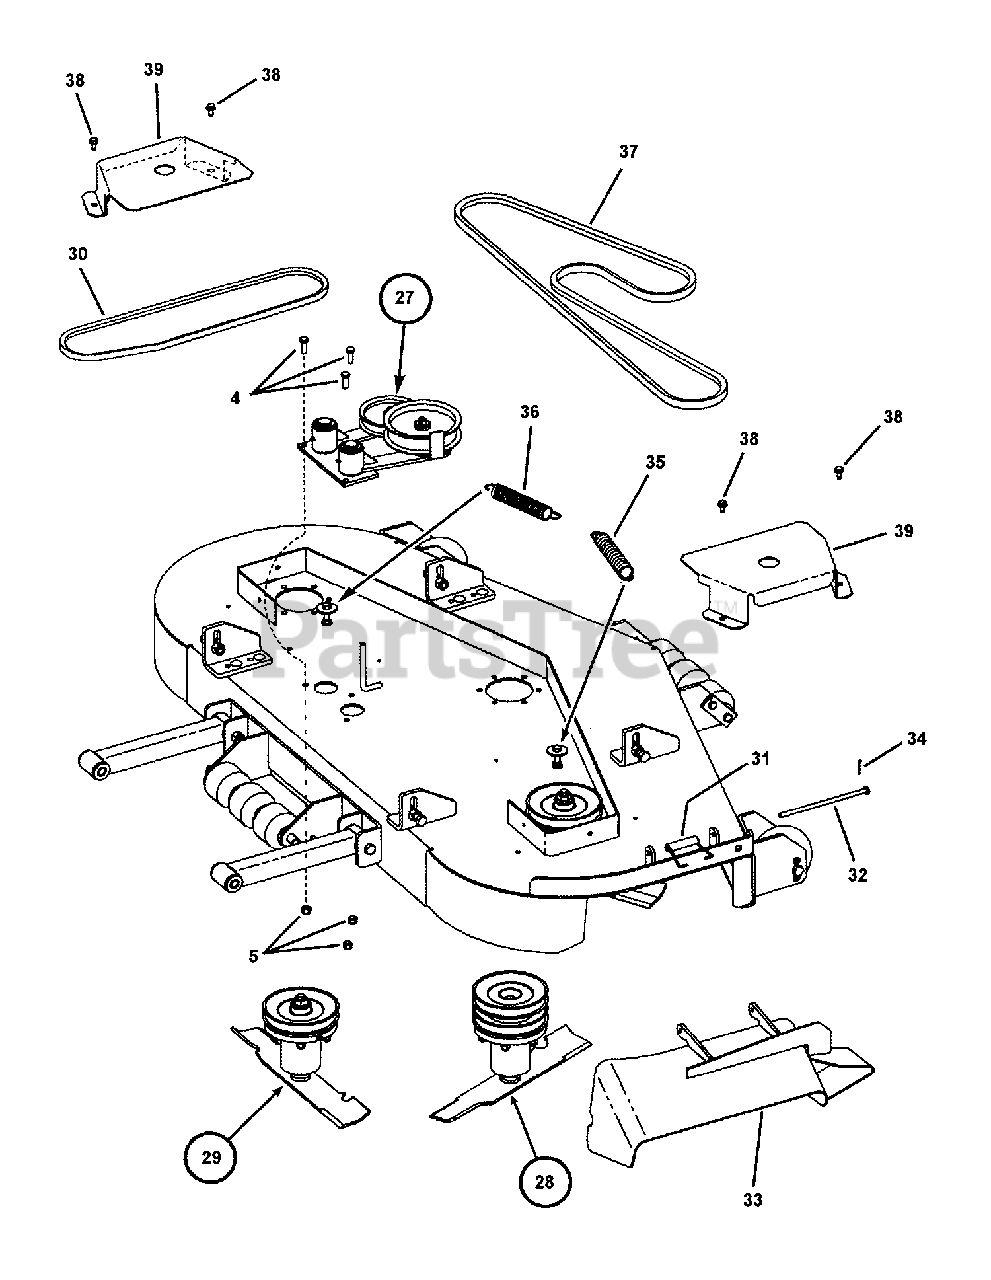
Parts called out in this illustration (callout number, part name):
4	BOLT, 3/8-16 X 1" GD5 CZ
5	NUT, 3/8-16 HEX NYLON LOCK
27	ASSEMBLY, Idler (see breakdown on Idler Assy page)
28	ASSEMBLY, Center Spindle (see breakdown on Deck Spindle Assy page)
29	ASSEMBLY, Spindle (see breakdown on Deck Spindle Assy page)
30	BELT, Primary (HB Section, 94.20" effective length)
31	SPRING, Chute
32	PIN, Chute Hinge
33	WELDMENT, Chute Deflector (61" Euro)
34	PIN, 3/32 x 1" Cotter
35	SPRING, Idler Primary (1.25" O.D. x 10" long)
36	SPRING, Idler (1.17" O.D. x 7.5" long)
37	V-BELT, Secondary- 61" (HB Section, 127.0" effective length)
38	SCREW, 5/16-18 x 5/8" Hex Washer Self-Tap
39	BELT COVER
